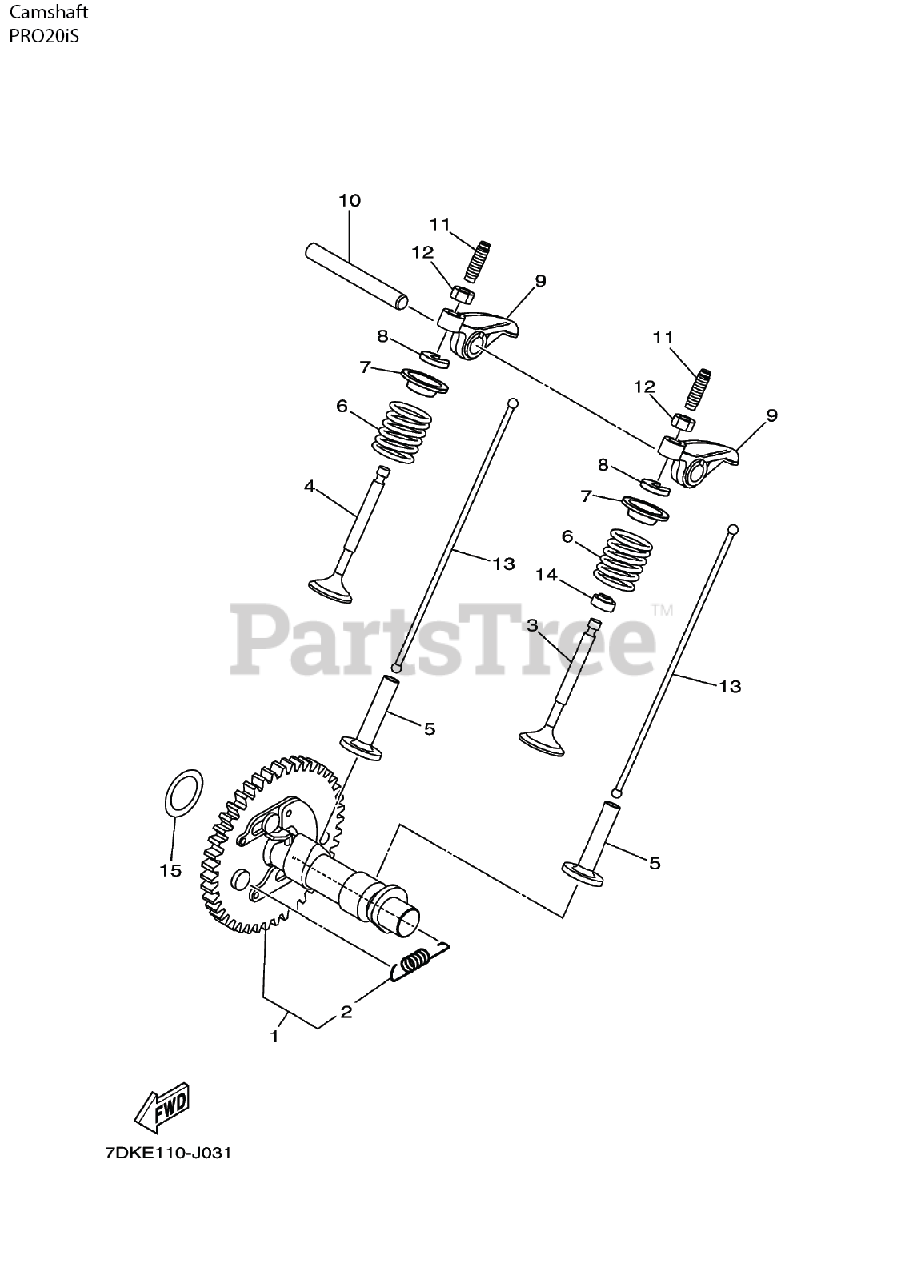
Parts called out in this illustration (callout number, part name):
1	CAMSHAFT ASSEMBLY
2	SPRING, DECOMPRESSION
3	VALVE, INTAKE
4	VALVE, EXHAUST
5	TAPPET, VALVE - LIFTER VALVE
6	SPRING, COMPRESSION
7	RETAINER, VALVE SPRING
8	LOCK, COTTER VALVE
9	ARM, VALVE ROCKER
11	SCREW - VALVE ADJUSTING
13	ROD, VALVE PUSH
14	SEAL, VALVE STEM
15	SHIM, CAMSHAFT
